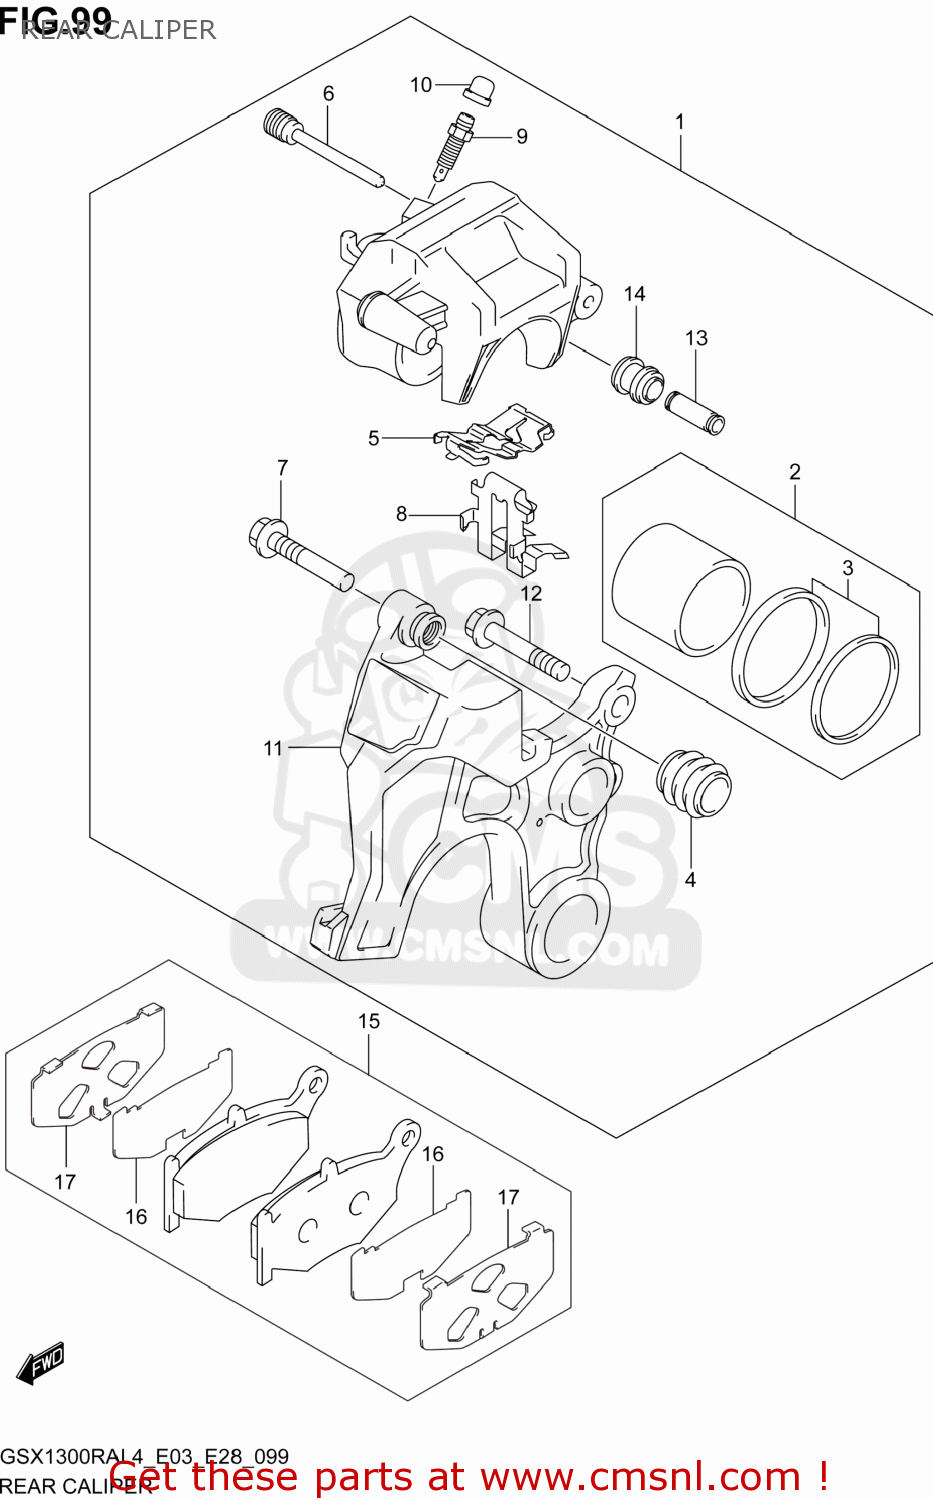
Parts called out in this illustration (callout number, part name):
1	CALIPER ASSY,REAR
2	PISTON SET
3	SEAL SET,PISTON
4	BOOT,AXLE
5	SPRING,PAD
6	PIN,PAD
7	PIN,BOLT
8	RETAINER
9	BLEEDER
10	CAP,BLEEDER PLUG
11	BRACKET
12	BOLT
13	SLEEVE
14	BOOT,SLEEVE
15	PAD & SHIM SET (NAS)
16	INSULATOR
17	SHIM
